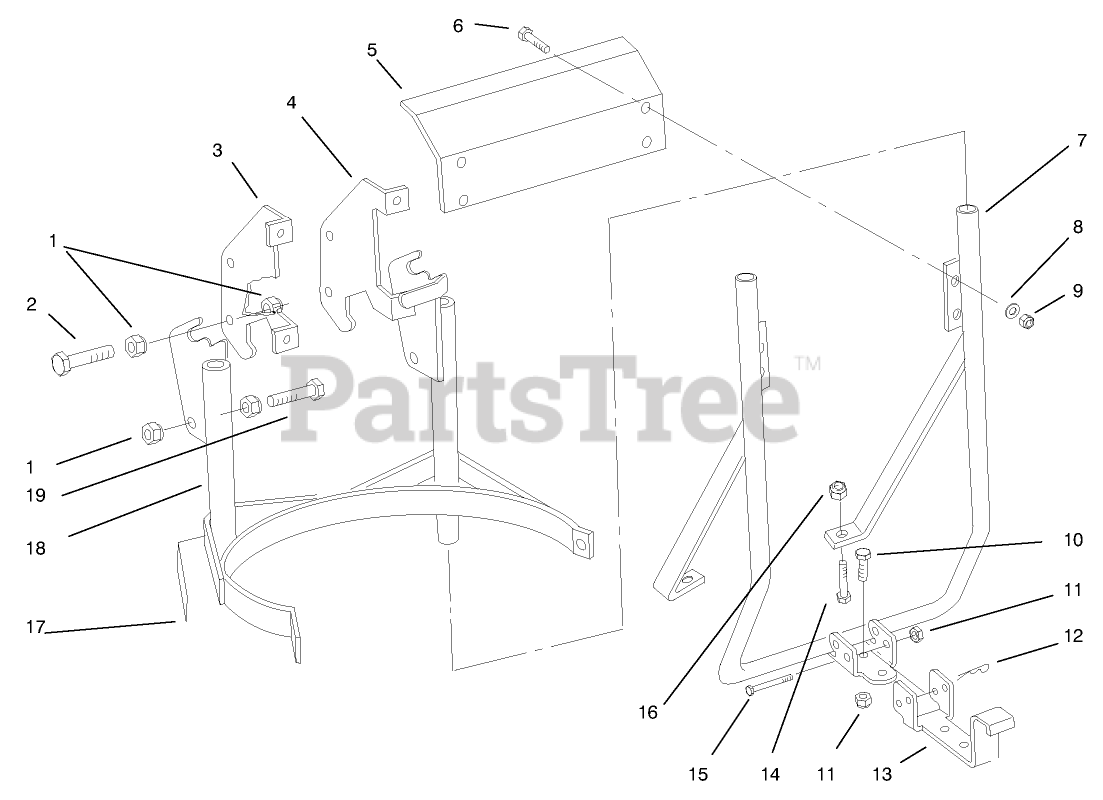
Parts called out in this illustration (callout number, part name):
1	NUT-HEX
2	SCREW-HH
3	LH TOP BRACKET B
4	RH TOP BRACKET B
5	SHIELD-HEAT B
6	SCREW-HH
7	WA - BAGGER MOUNT
8	WASHER-PLAIN
9	NUT-LOCK, NI
10	SCREW-HH
11	NUT-LOCK, NI
12	PIN-COTTER, HAIR
13	BRACKET-SUPT B
14	SCREW-HH
15	SCREW-HH
16	NUT-LOCK, NI
17	DECAL-DANGER
18	WA-CANISTER SUP W/DECALB
19	Screw
